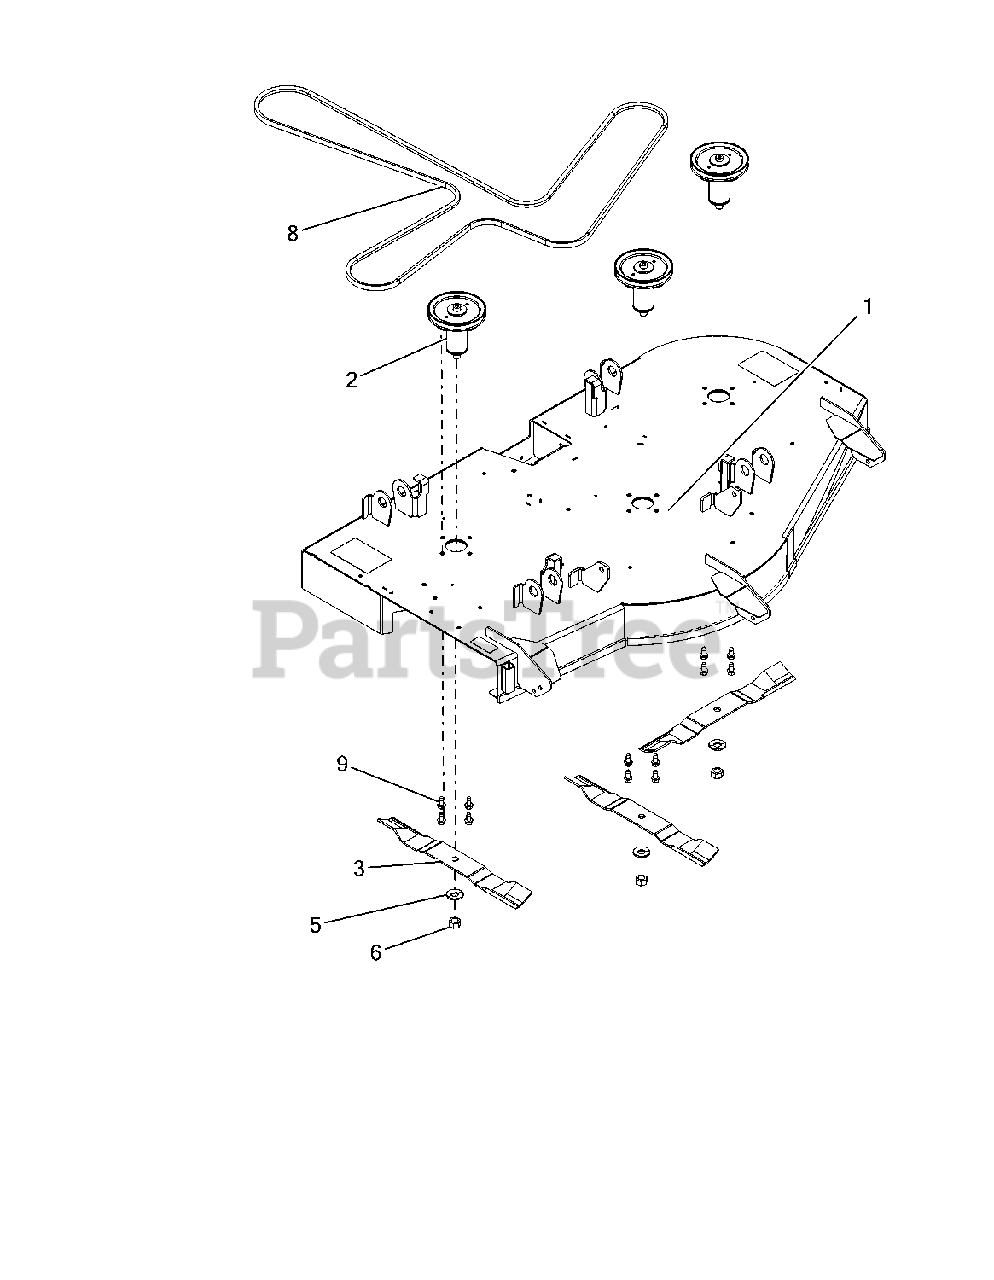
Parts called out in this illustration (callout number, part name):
1	KIT, 52" ARIENS DECK W/DECALS
2	KIT, DECK SPINDLE ASM-52
3	BLADE, 18" - 30 DEG .5 OFFSET
5	WSHR-BLVL .669X1.535X.138
6	NUT-HEX .62-18 YWZC
8	V-BELT, HA-WRAPPED
9	@SCR-TAP .38-16X.75 HWH TR YWZ
